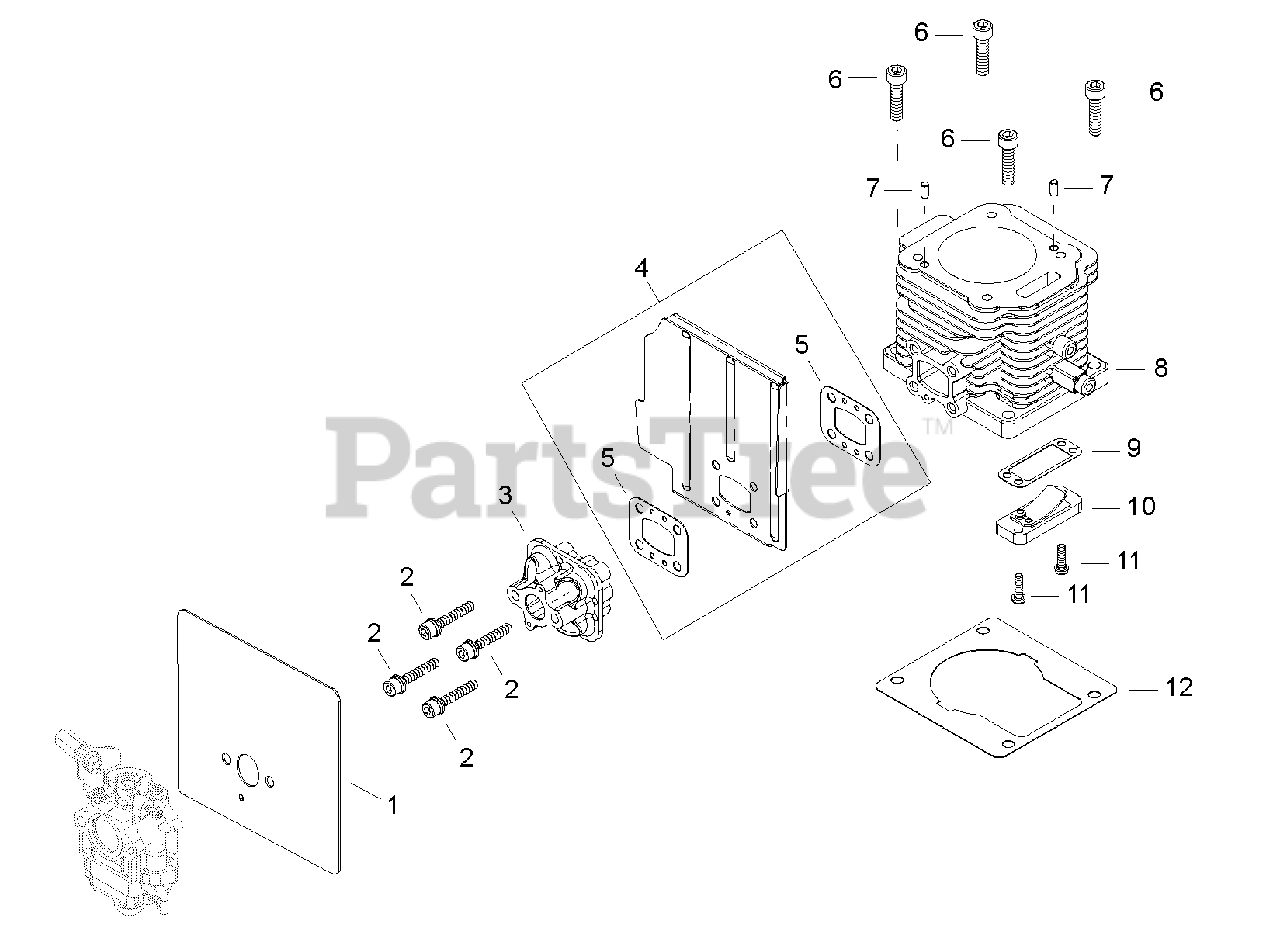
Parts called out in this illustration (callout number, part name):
1	GASKET
2	SCREW - 5X30
3	INSULATOR
4	INTAKE SHIELD KIT
5	GASKET, INTAKE
6	SCREW - 6X25
7	PIN - LOCATING
8	CYLINDER
9	GASKET
10	REED VALVE ASSY
11	SCREW - 4X14
12	GASKET
